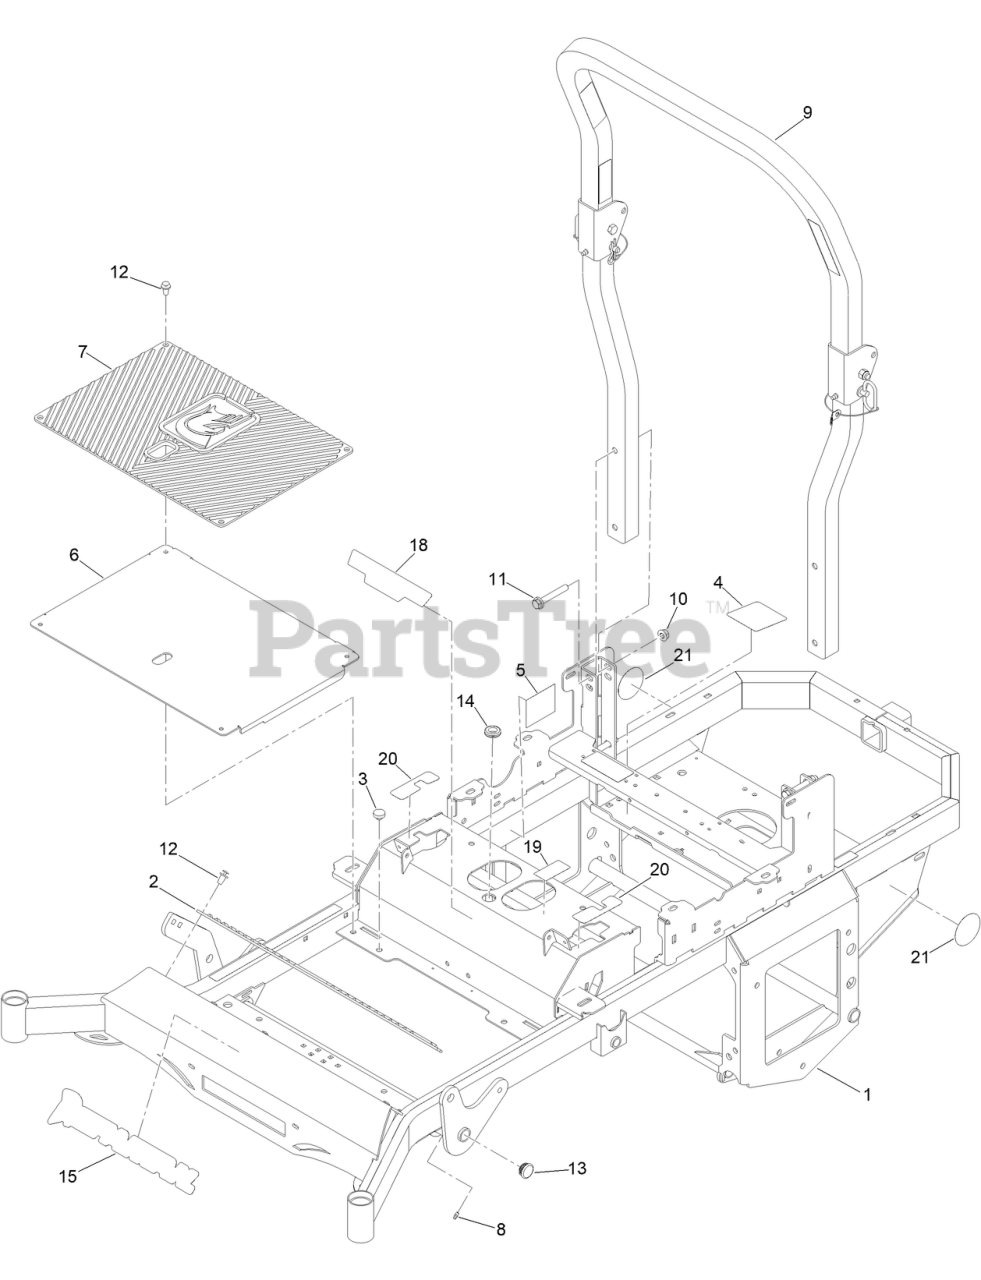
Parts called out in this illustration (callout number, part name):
1	FRAME ASM W/ DECALS
2	MWR RUBBER FOOT REST MAT
3	PUSH-IN RUBBER BUMPER MWR FLOOR
4	DECAL-PUMP BELT ROUTING-PARKER
5	DECAL-E P A
6	MWR FLOORBOARD PAINT
7	MWR LOGO FLOOR MAT
8	1/4 DRIVE TYPE STRAIGHT GREASE FITTNG ZC
9	SPARTAN FOLDING ROPS BOXED
10	1/2-13 HEX STOVER LOCKNUT GR C ZINC
12	8MM PUSH TYPE RETAINER NYLON BLACK
13	1-1/4 IN ROUND TUBE PLUG
14	GROMMET-RUBBER
15	DECAL-SPARTAN, FRONT
18	2022 SRT-XD W/GT TRAC DECAL
19	DECAL-WEIGHT, SEAT
20	DECAL-MOTION CONTROL
21	MWR PARKER PUMP DECAL
